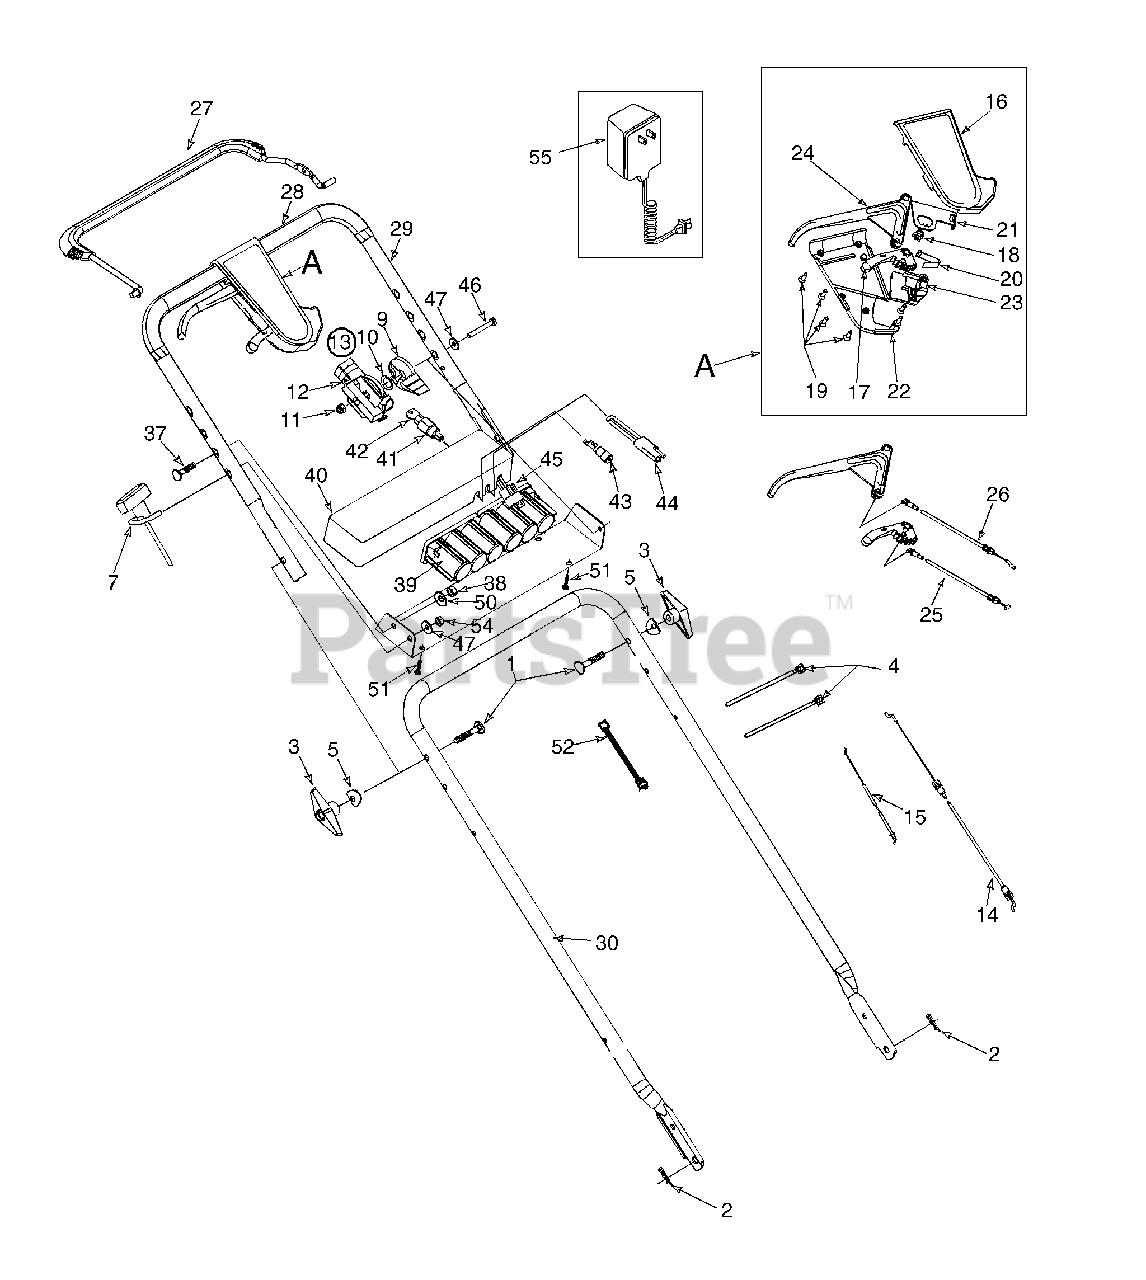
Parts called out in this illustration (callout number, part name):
1	Bolt Cur. Carr. 5/16-18 x 2.0
2	Cotter Pin .072 x 1.12 Lg.
3	Knob Assembly
4	Strap 4.3 Lg.
5	Wash. Sad. .320 ID x.830 OD
9	Throttle Lever
10	Spring Wash.Curved
11	Nut 1/4-20 Top locknut Insert
12	Housing, Throttle
13	Throttle Control
14	Control Cable 47" Lg.
15	Cable Throttle 60" Lg.
16	Upper Control Housing
17	6 Speed Shift Lever
18	Gear Insert
19	C Sunk Tap Screw #10 x .75 L
20	Shift Lever Spring
21	6 Spd. Rack Cable Brkt.
22	Lower Control Housing
23	Cable Mounting Cap
24	Control Lever
25	6 Spd. Cable
26	S.P. Cable
28	Foam Grip (2 Reqd.)
37	Cur. Carr. Bolt 5/16-18 x 1" Lg.
38	Hex Nut 5/16-18 Thd.
39	Battery Pack - 12 Volt
40	Battery Tray
41	Ignition Switch
42	Ignition Key
43	Fuse Holder
44	Plug
45	Wire Harness
46	Hex Bolt 1/4-20 x 2" Lg.
47	Bell Wash 1/4" I.D.
51	Truss Mch. Tap Scr. 1" Lg.
52	Harness Ext.
54	Hex Nut 1/4-20
55	Battery Charger
